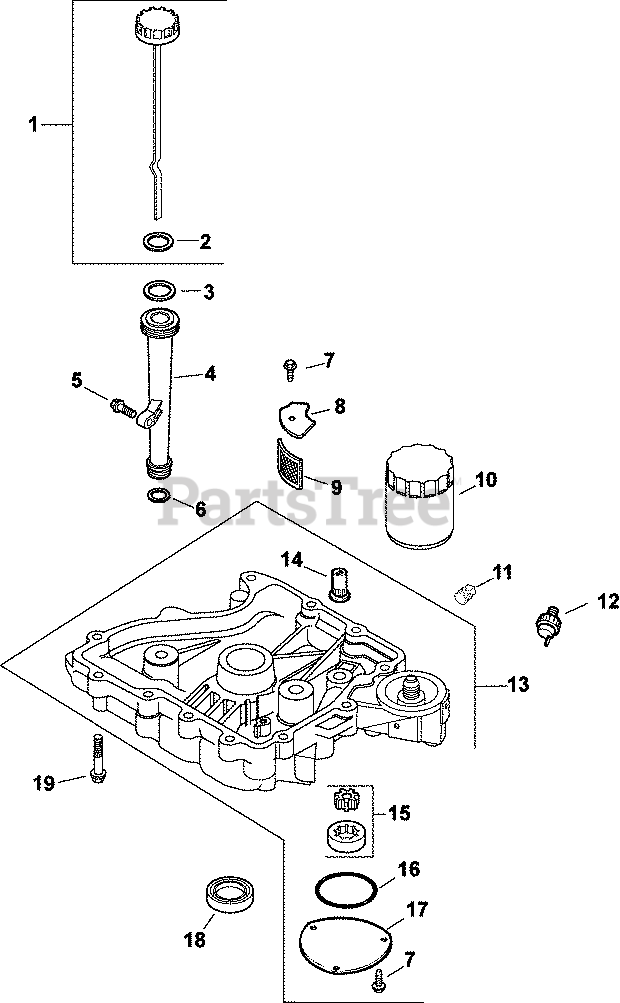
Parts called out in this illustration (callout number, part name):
1	DIPSTICK/CAP ASSY (BLACK)
2	O-RING, DIPSTICK
3	O-RING, UPPER OIL FILL TUBE
4	TUBE, OIL FILL USE 25 123 07-S
5	SCREW, FLG THD FRM M5X.8X20-(#25086399S)
6	O-RING, LOWER OIL FILL TUBE
7	SCREW,FLG THD FRM M5X0.8X16-(#25086398S)
9	SCREEN, OIL-USE 24 162 26-S
10	OIL FILTER
11	PLUG, SQ HD PIPE 3/8"
12	SENSOR, OIL PSI
13	PAN, OIL
14	VALVE, OIL PRESSURE RELIEF
15	PUMP ASSEMBLY, OIL - DISCONTINUED
16	O-RING (2.5" DIA)
17	COVER, OIL PUMP
18	SEAL, OIL
19	SCREW, FLG M8X1.25X45
